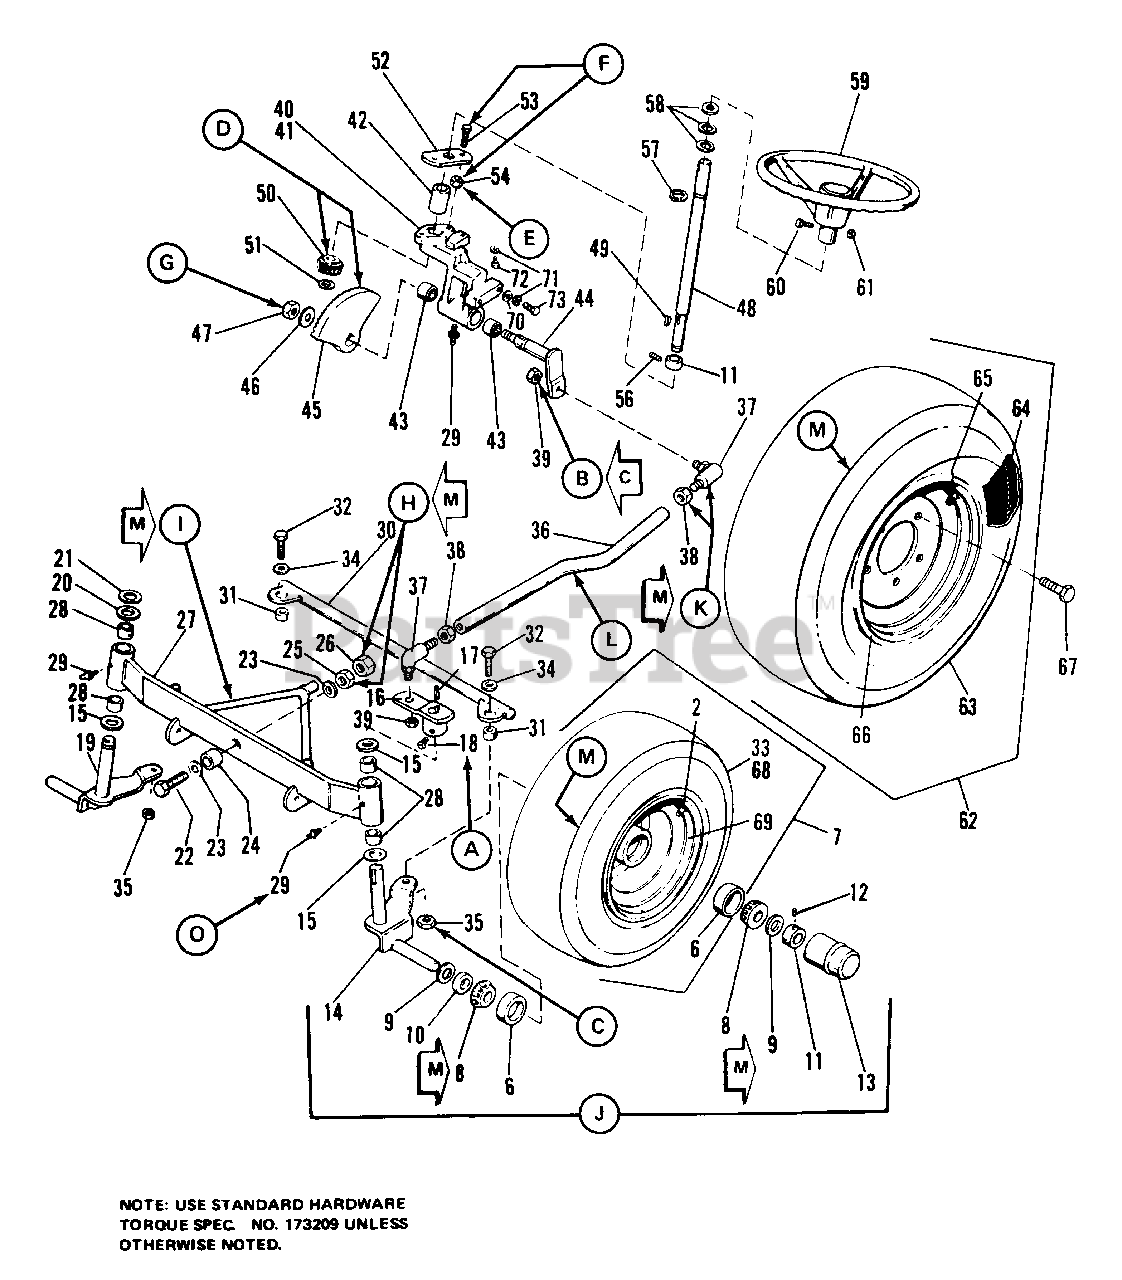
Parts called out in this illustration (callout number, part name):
2	VALVE STEM & CAP
6	CUP, Bearing (7010 Only)
7	WHEEL & TIRE ASSY
8	CONE, Bearing
11	COLLAR, Set
12	SETSCREW, Sq. Hd., Cup Pt., 5/16-18 x 5/16
13	CAP, Hub
14	SPINDLE ASSY, LH.
16	ARM, Steering L.H.
17	KEY, Square
18	SETSCREW, 5/16-18 x 1/2
19	SPINDLE ASSY, R.H.
21	"E" RING, External
22	CAPSCREW, Hex Hd., 1/2-13 x 2-1/4
23	WASHER, Plain, 1/2
25	LOCKNUT, Hex, 1/2-13
26	NUT, Jam Hex, 1/2-13
27	FRONT AXLE ASSY
29	FITTING, Grease
30	TIE ROD ASSY
32	CAPSCREW, Hex Hd., 3/8-16 x 1-1/4
33	TIRE, 16x6.50-8, Goodyear
33	TIRE, 16x6.50-8, Carlisle
34	WASHER, Plain, 3/8
35	LOCKNUT. Hex, 3/8-16
36	LINK, Drag
37	JOINT, Ball
38	NUT, Jam Hex, 1/2-20
39	LOCKNUT, Hex, 1/2-20
40	STEERING HOUSING ASSY,(Incl. Ref. No's 41, 42 & 43)
41	HOUSING, Steering
43	BEARING, Needle
44	STEERING ARM ASSEMBLY
45	GEAR, Bevel
46	WASHER, Plain, 7/16
47	LOCKNUT, Hex, 7/16-14
48	SHAFT, Steering
49	KEY, Woodruff, No. 6, 5/32 x 5/8
50	PINION, Bevel
51	"E" RING
52	PLATE, Steering
53	CAPSCREW, Hex Hd., 3/8-16 x 1-1/4
54	LOCKNUT, 3/8-16
56	SETSCREW, Sq. Hd., 5/16-18 x 1/4
57	RING, Retaining
59	WHEEL, Steering
60	CAPSCREW, Hex Hd., 5/16-18 x 1-1/4
61	LOCKNUT, Flange, 5/16-18
62	WHEEL & TIRE ASSEMBLY (7010 Only)
62	WHEEL & TIRE ASSY. (1690423 Only)
62	WHEEL & TIRE ASSY, R.H. (1690425 Only)
62	WHEEL & TIRE ASSY., L H. (1690425 Only)
63	TIRE, 23-8.50 x 12, Goodyear (7010 Only)
63	TIRE, 23-8.50 x 12 Carlisle (7010 Only)
63	TIRE, Turf, 23-10.50, Carlisle (1690423 Only)
63	TIRE, Turf, 23-10.50, Firestone (1690423 Only)
63	TIRE, Ag., 23-10 50 (1690425 Only)
64	TUBE (7010 Only)
64	TUBE (7016 Only)
65	STEM & VALVE CAP (7010 Only)
66	WHEEL, Drive (7010 Only)
68	TUBE, (7016 0nly)
69	WHEEL ASSY (7016 Only)
70	WASHER, Plain, 3/8
71	LOCKWASHER, Spring, 3/8
72	CAPSCREW, Hex Hd., 3/8-16 x 3/4
73	CAPSCREW, Hex Hd., 3/8-16 x 7/8
